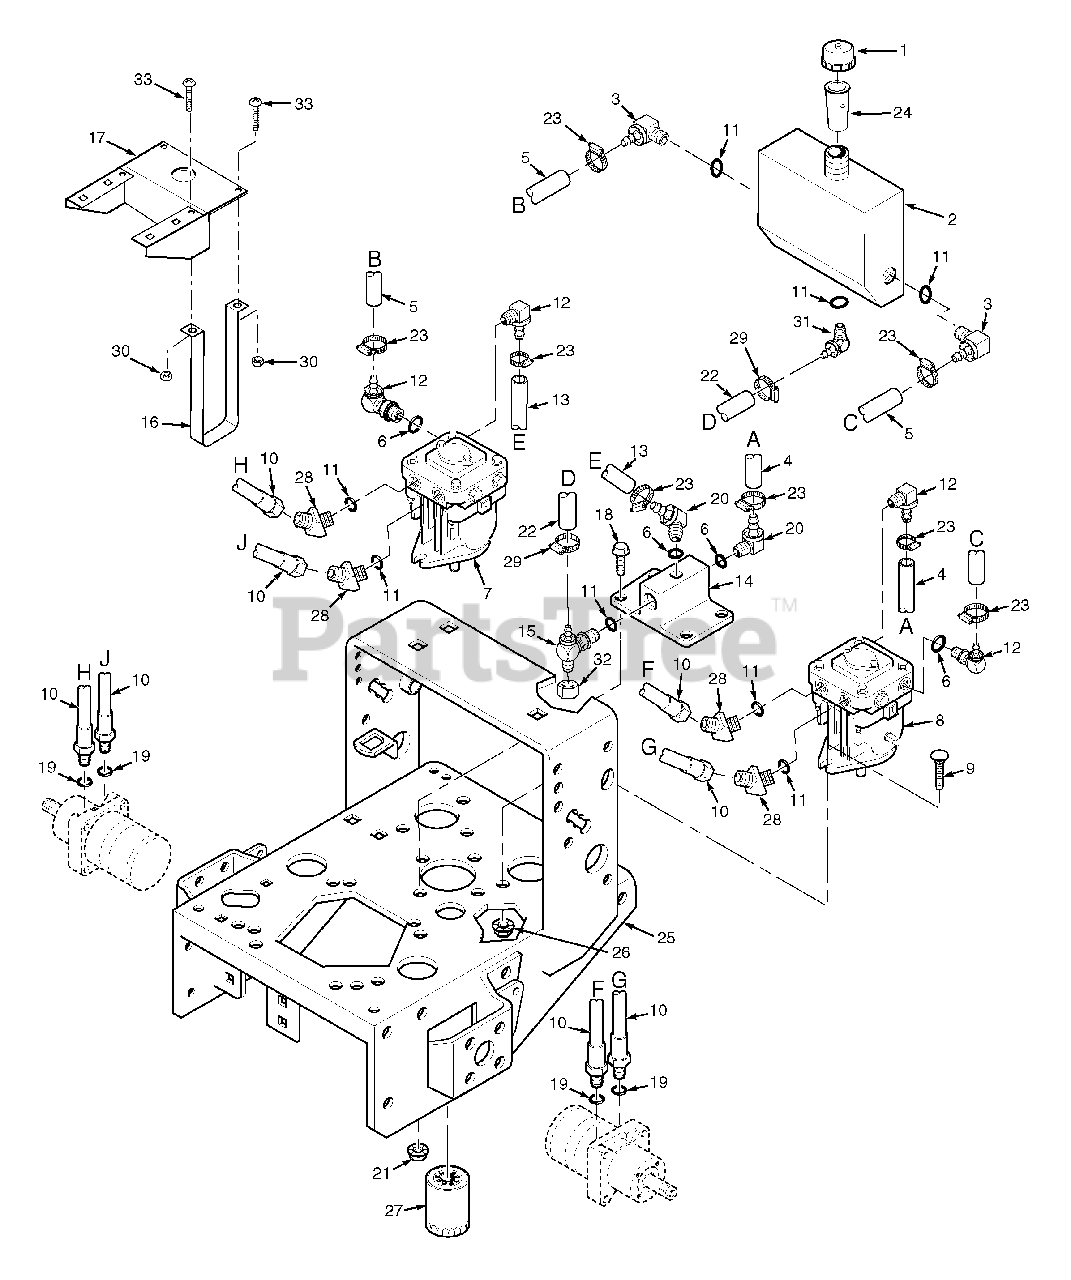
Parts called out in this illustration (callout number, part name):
1	Cap, Oil Reservoir
2	Oil Reservoir (With Fittings)
3	Elbow, 9/16 O-Ring x 3/8 Hose
4	Hose, 3/8" ID - 10-1/4" Long
5	Hose, 3/8" ID - 7" Long
6	O-Ring
7	Pump, PG-1JQQ-DY1X-XXXX (R.H.)
8	Pump, PG-1GQQ-DY1X-XXXX (L.H.)
9	Bolt, Carriage, 3/8-16 x 1.25"
10	Hose, Pump to Wheel Motor
11	O-Ring
12	Elbow, 7/16-20 O-Ring x 3/8 Hose
13	Hose, 3/8" ID - 11" Long
14	Oil Filter Base
15	Tee, 3/8 O-Ring x JIC x 1/2 Hose
16	Strap, Hydraulic Tank
17	Bracket, Hydraulic Tank
18	Capscrew, 5/16-18 x .75" Serr. Flange
19	O-Ring
20	Elbow, 9/16 O-Ring x 3/8 Hose
21	Nut, 5/16-18 Serr. Flange
22	Hose, Formed 1/2" ID
23	Clamp, .69 max dia.
24	Tube, Filler Neck
25	Engine Deck (16" Wide) with Decals - Small Frame
26	Nut, 3/8-16 Serr. Flange
27	Oil Filter
28	Elbow, 45 Deg.-3/4-16 JIC Male x Male 3/4-16 O-Ring
29	Clamp, .87 max di.
30	Nut, 1/4-20
31	Elbow, 3/4-16 O-Ring x 1/2 Hose
32	Cap, 3/4-16
33	Screw, 1/4-20 x 2.0" Round Head Phillips
